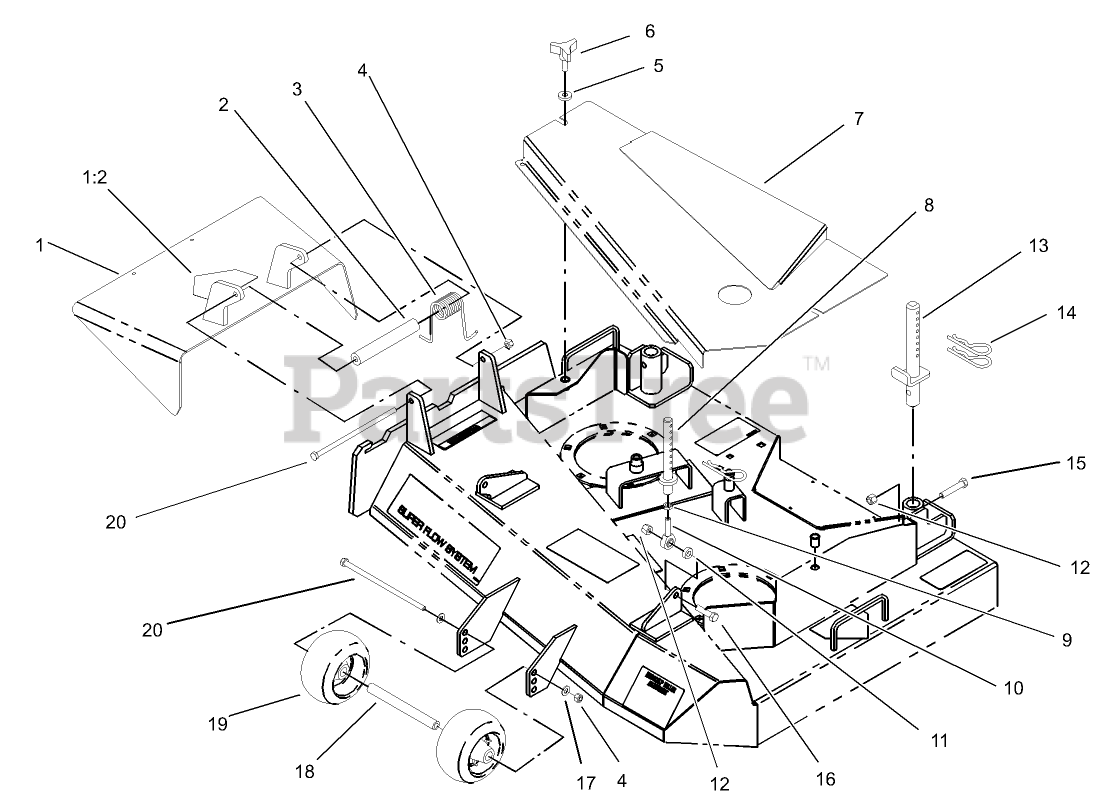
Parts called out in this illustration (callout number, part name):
1	Deflector ASM
1:2	DECAL-DANGER
2	SPACER
3	SPRING-TORSION
4	NUT-LOCK, NI
5	WASHER-RUBBER
7	Cover ASM
8	FRONT PIN ASM
9	NUT-HJ
10	BALLJOINT
11	SPACER
12	NUT-LOCK, NI
13	REAR PIN ASM
14	PIN-HAIR
15	SCREW-HH
16	SCREW-HH
17	WASHER-PLAIN
18	SPACER-WHEEL
19	WHEEL-GAGE
20	SCREW-HH
